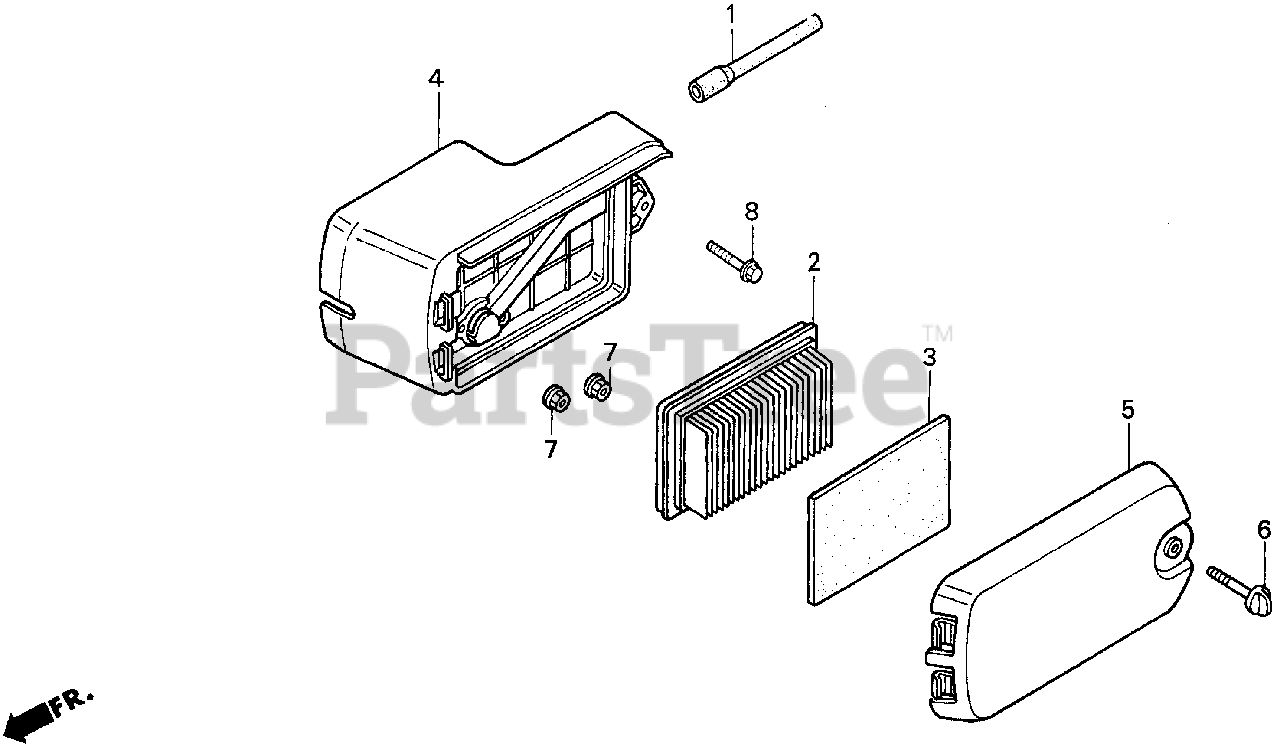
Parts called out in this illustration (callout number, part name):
1	TUBE, BREATHER (110MM)
2	ELEMENT, AIR CLEANER
3	FILTER (OUTER)
4	HOUSING, AIR CLEANER
5	COVER, AIR CLEANER
6	BOLT, AIR CLEANER (6MM)
7	NUT, FLANGE (6MM)
8	BOLT, FLANGE (6X32)
